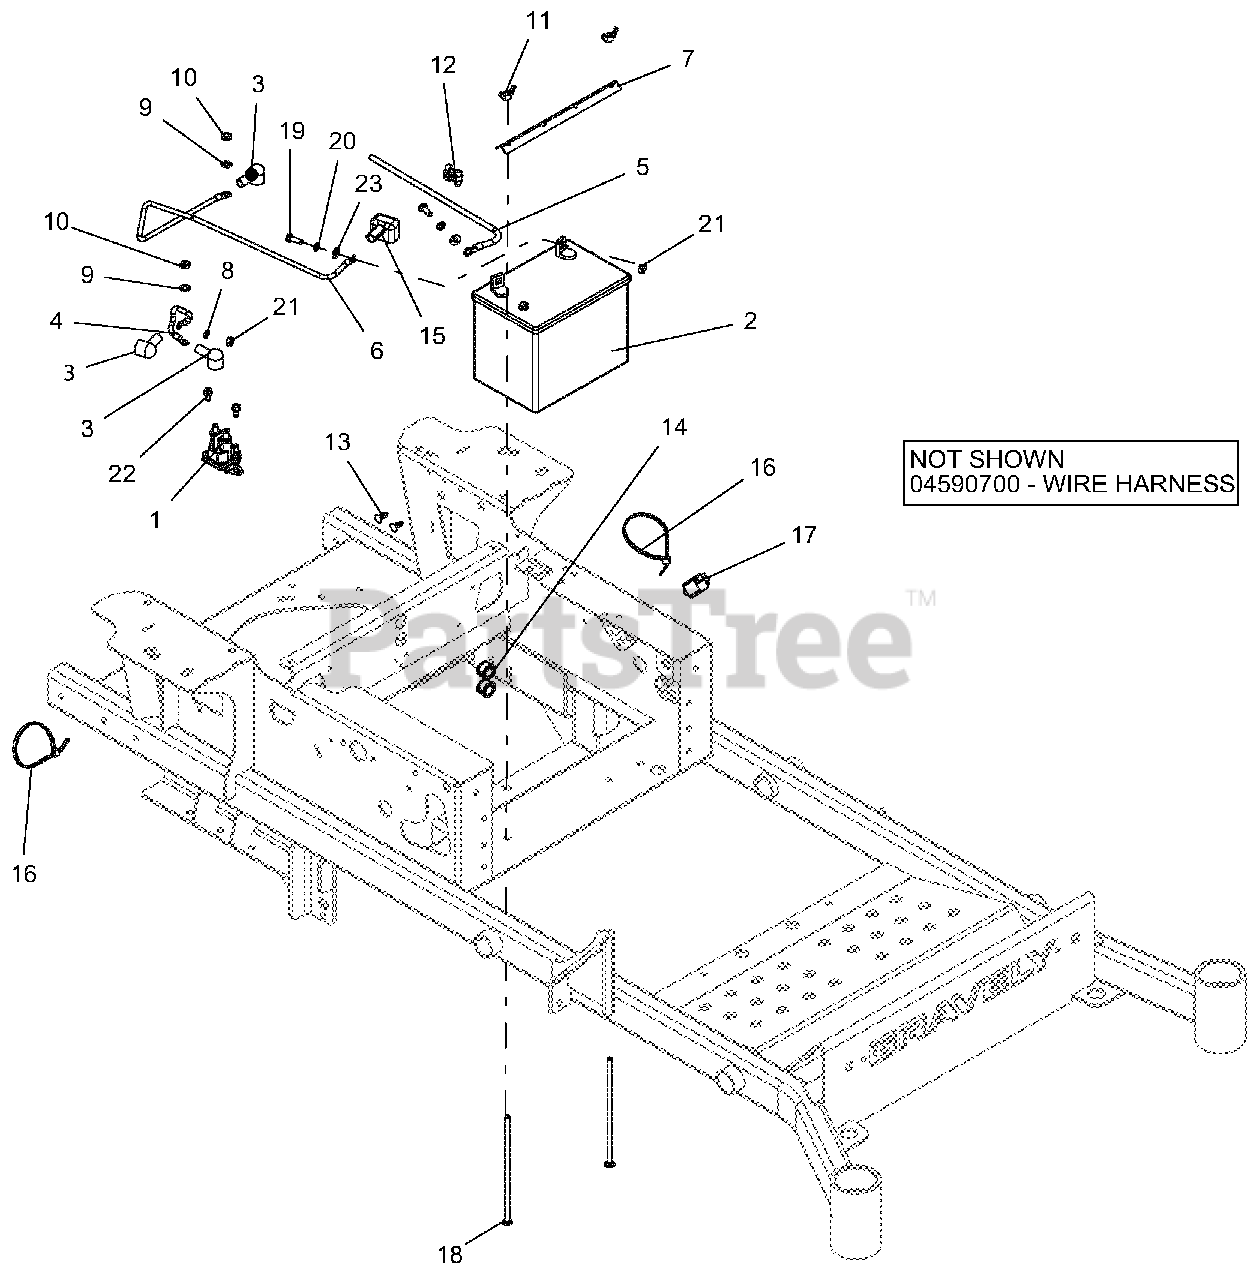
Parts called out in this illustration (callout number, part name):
1	SOLENOID, HP RTV
2	BATTERY, 300 CCA 10U1L
3	BOOT, EYELET TERMINAL
4	CABLE, POSITIVE BATTERY 9.00"
5	CABLE, NEGATIVE BATTERY 24"
6	CABLE, STARTER .31 X 23.00 X .31
7	HOLD DOWN - BLK
8	@, WSHR-LK-EXT.262X.502X.026 YWZC
9	WSHR-LK-EXT .326X.599X.031 YWZC REV
10	NUT-JAM
11	NUT-LOCKING WING 1/4-20
12	CLIP, T, .318-.3
13	RIVET, .25 NYLON PANEL
14	BUSH, PANEL SNAP .687X.875X.56
15	INSULATOR
16	CABLE, TIE 5.50 LG
17	SWITCH, SINGLE POLE N.O.
18	BLT-RDHDSQNK .25-20X7.50 G2 YWZC
19	BLT-HEX .25-20X.75 GR5 YWZC
20	WSHR-LK .25X.062 REG YWZC
21	NUT-HEX .25-20 YWZC
22	SCR-TAP .25-20X.50 HWH TR YWZ
23	WSHR-FL-STL.281X.62X.065 YWZC
